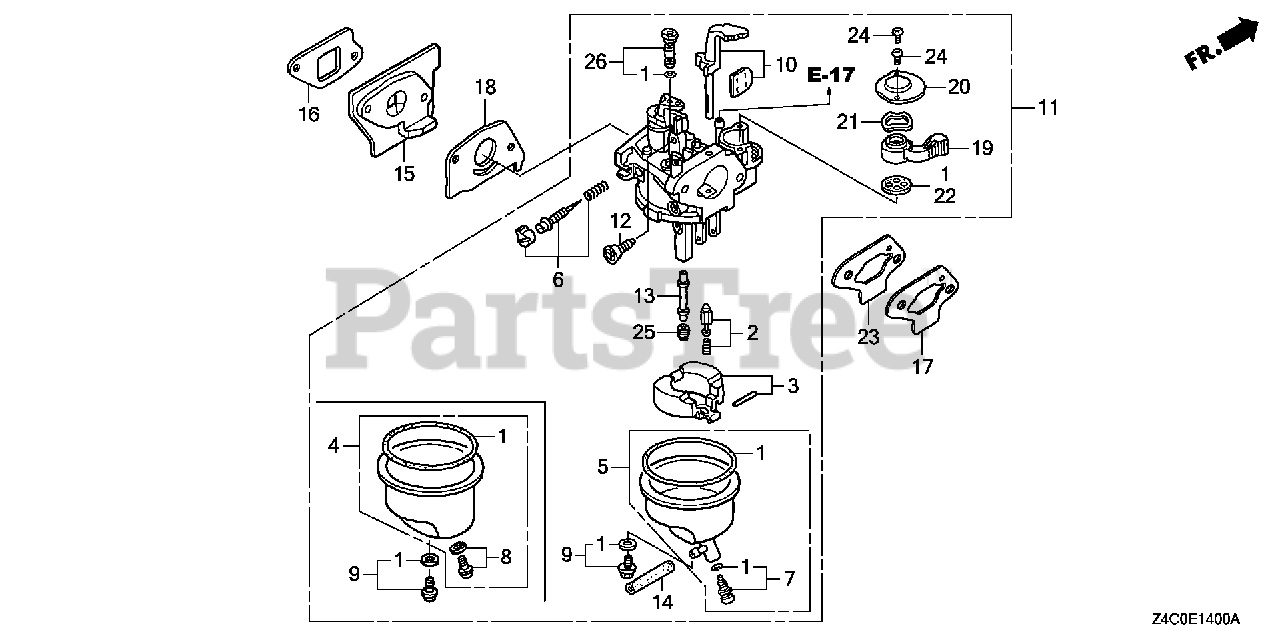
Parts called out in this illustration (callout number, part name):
1	GASKET SET
2	VALVE SET, FLOAT (SEAT NOT INCLUDED)
5	CHAMBER SET, FLOAT
6	SCREW SET, PILOT (CARBURETOR NO.)
7	SCREW SET, DRAIN
9	SCREW SET
11	CARBURETOR ASSY. (BF32G A)
12	SCREW, THROTTLE STOP
13	NOZZLE, MAIN
14	BULK HOSE, VINYL (3.5X6.5X8000) (3.5X6.5X100)
15	INSULATOR, CARBURETOR
16	GASKET, INSULATOR
17	SPACER, CARBURETOR
18	GASKET, CARBURETOR
19	LEVER, PETCOCK
20	PLATE, LEVER SETTING
21	SPRING, PETCOCK LEVER
22	GASKET, PETCOCK
23	GASKET, AIR CLEANER
24	SCREW, PAN (3X6)
25	JET, MAIN (#48)
25	JET, MAIN (#50)
25	JET, MAIN (#52)
26	JET SET, PILOT (#35)
